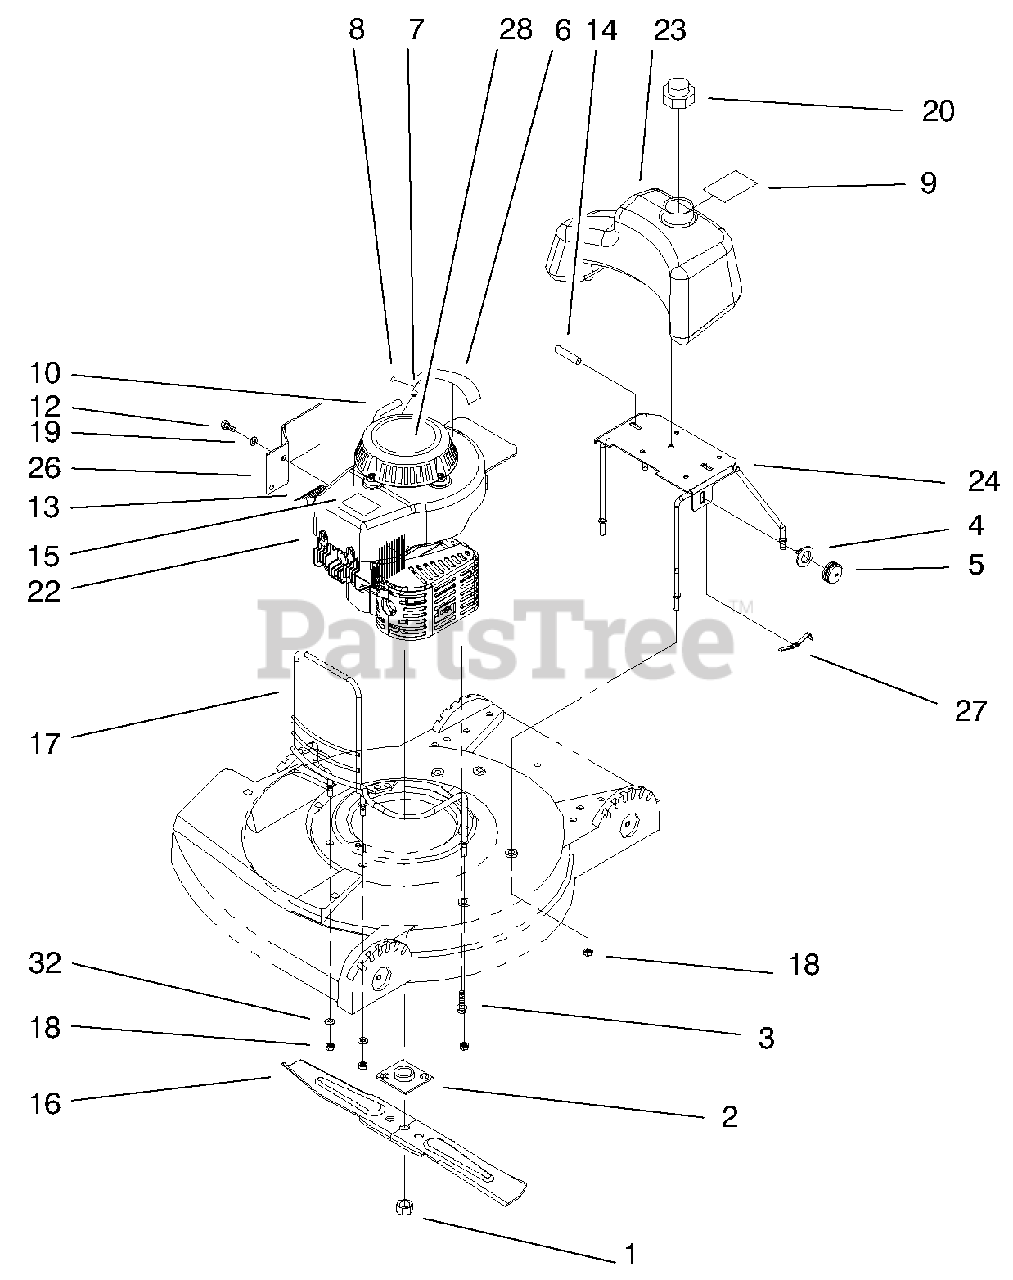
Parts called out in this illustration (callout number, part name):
1	Nut-Blade
2	ASM-Plate & Collar
3	Screw-Sems
4	Body-Primer
5	Bulb-Primer
6	Decal-Fuel Mix
7	Rope Stop
10	Gas Line
12	Screw-HH
13	Spring-Compression
14	Plug-Fuel Line
15	Decal-Lawn Boy
16	Blade-21" Whirl
17	Guard-Engine
18	Locknut
19	Washer-Lock
20	ASM-Fuel/Oil Cap
22	Engine Commercial Hp Dom
23	Tank-Fuel
24	Tank Bkt ASM
26	Guard-Brake
28	Decal-Recoil
29	Screw-Throttle Cable
30	Nut-Throttle Cable
32	Washer-Flat
